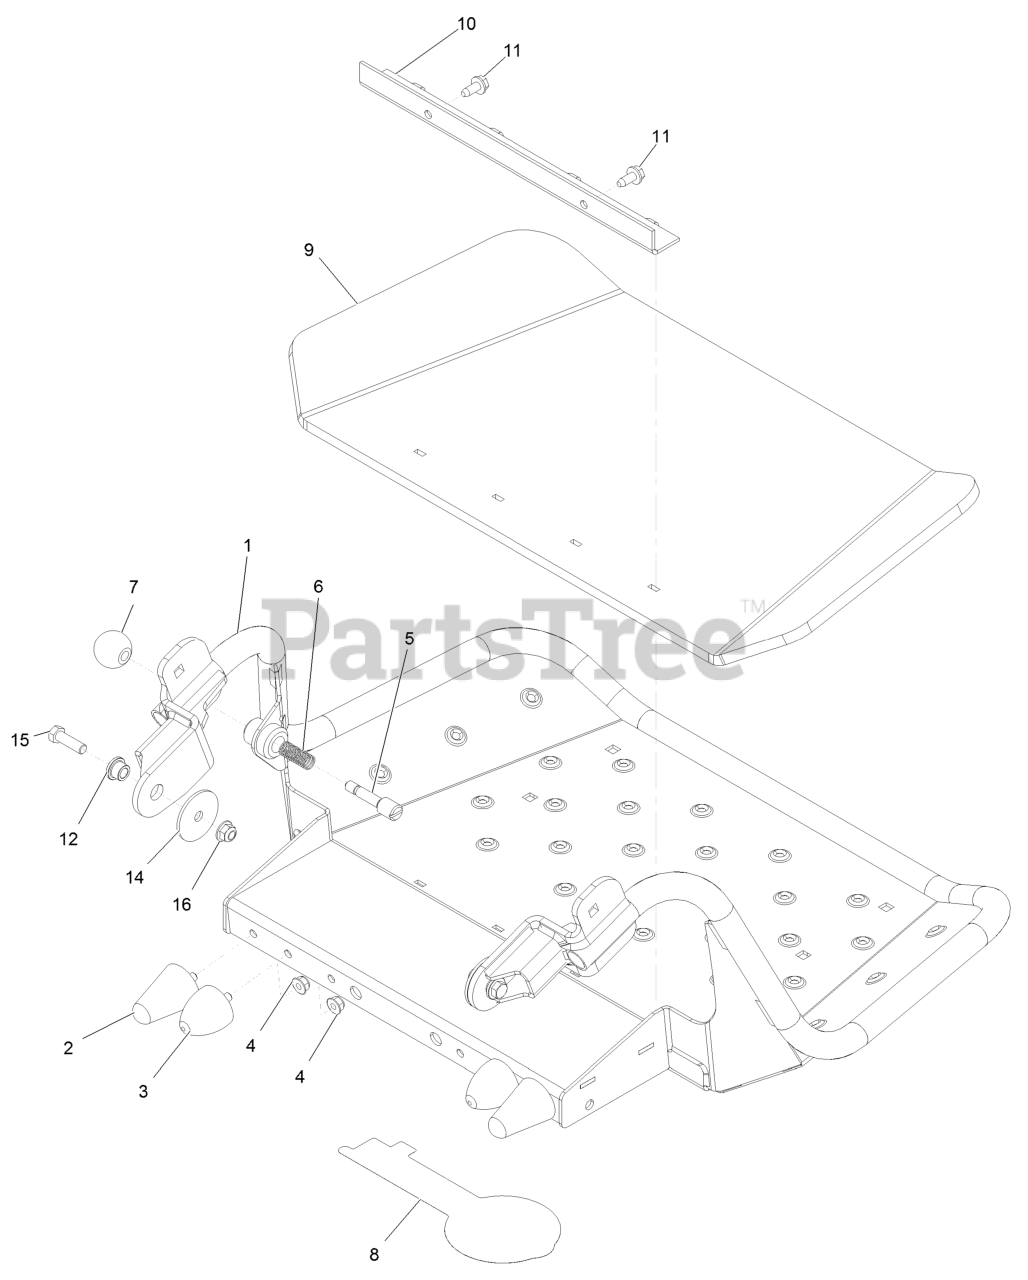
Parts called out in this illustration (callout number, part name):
1	PLATFORM ASM
2	BUMPER-RUBBER
3	BUMPER-RUBBER
4	NUT-HF, NI
5	PIN-LATCH
7	KNOB-BALL
8	DECAL-EXMARK LOGO
10	CLAMP-SHIELD
11	Screw-HWH 5/16-18 X 3/4 Tf
12	BUSHING-FLANGED
14	WASHER-FLAT
15	SCREW-HH
16	NUT-HF, NI
